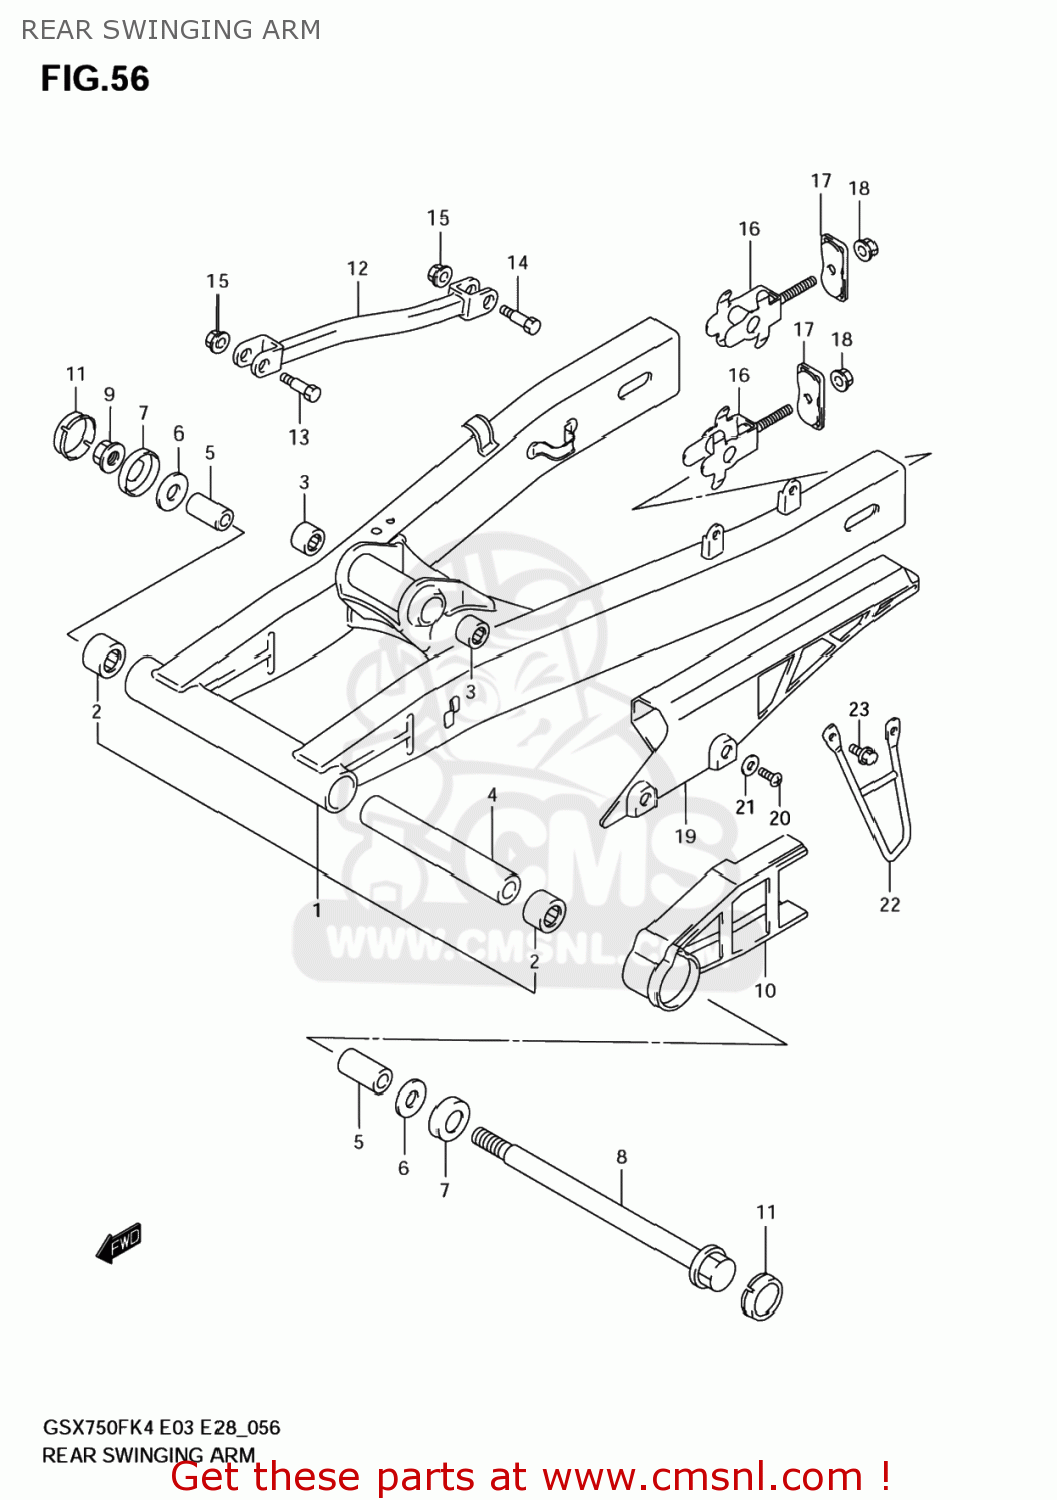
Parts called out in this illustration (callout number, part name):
1	SWINGINGARM ASSY,RR
2	BEARING(22X29X30)
3	BEARING(20X27X23.5)
4	SPACER,RR SWGARM PIVOT CTR
5	SPACER,RR SWGARM PIVOT
6	WASHER
7	COVER,RR SWGARM DUST SEAL
8	SHAFT,RR SWINGINGARM PIVOT
9	NUT
10	BUFFER,CHAIN TOUCH DEFENSE
11	CAP,SWINGINGARM PIVOT
12	TORQUELINK,RR
13	BOLT(10X39)
14	BOLT(10X34)
15	NUT
16	ADJUSTER,CHAIN
17	PLATE,CHAIN ADJ GUIDE
18	NUT
19	CASE,CHAIN
20	SCREW 6X12
21	WASHER
22	GUARD,CHAIN
23	BOLT
